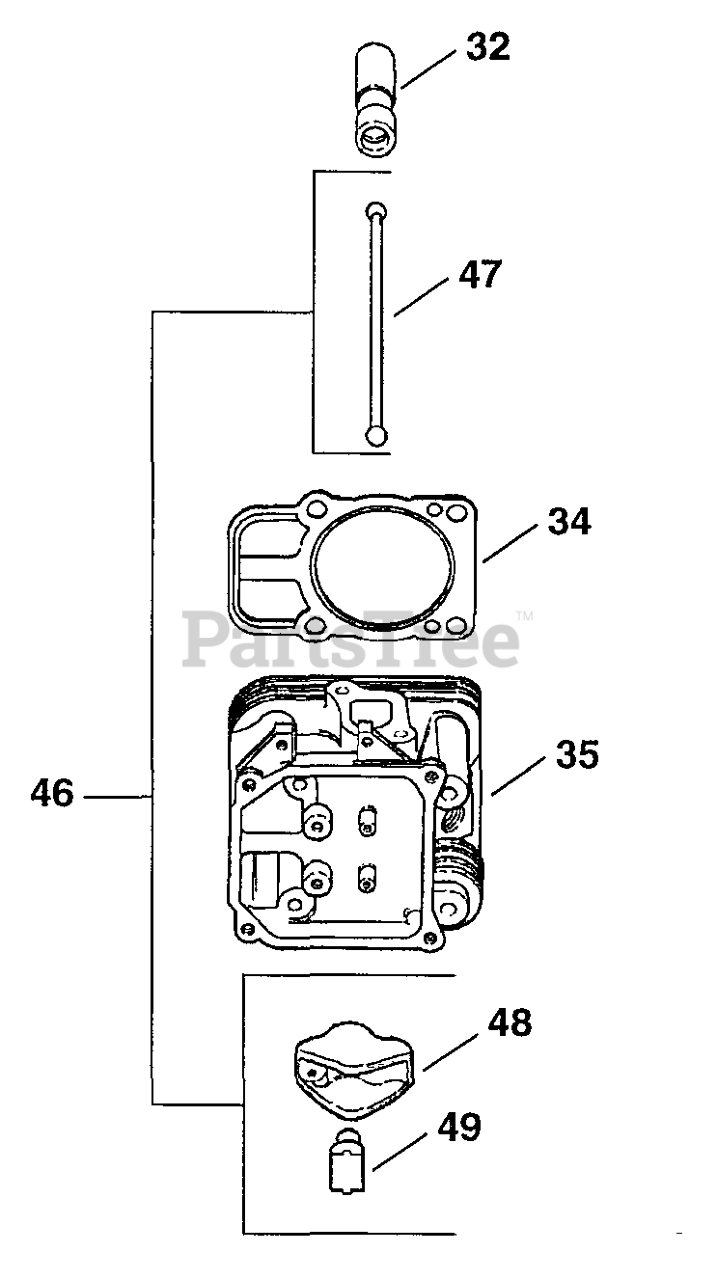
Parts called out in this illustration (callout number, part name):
32	Lifter, Valve
34	Gasket, Cylinder Head
35	Head Assembly, #2 Cylinder
46	Kit, Valve Train
47	Rod, Push
48	Arm, Rocker
49	Pivot, Cylindrical Rocker Arm
